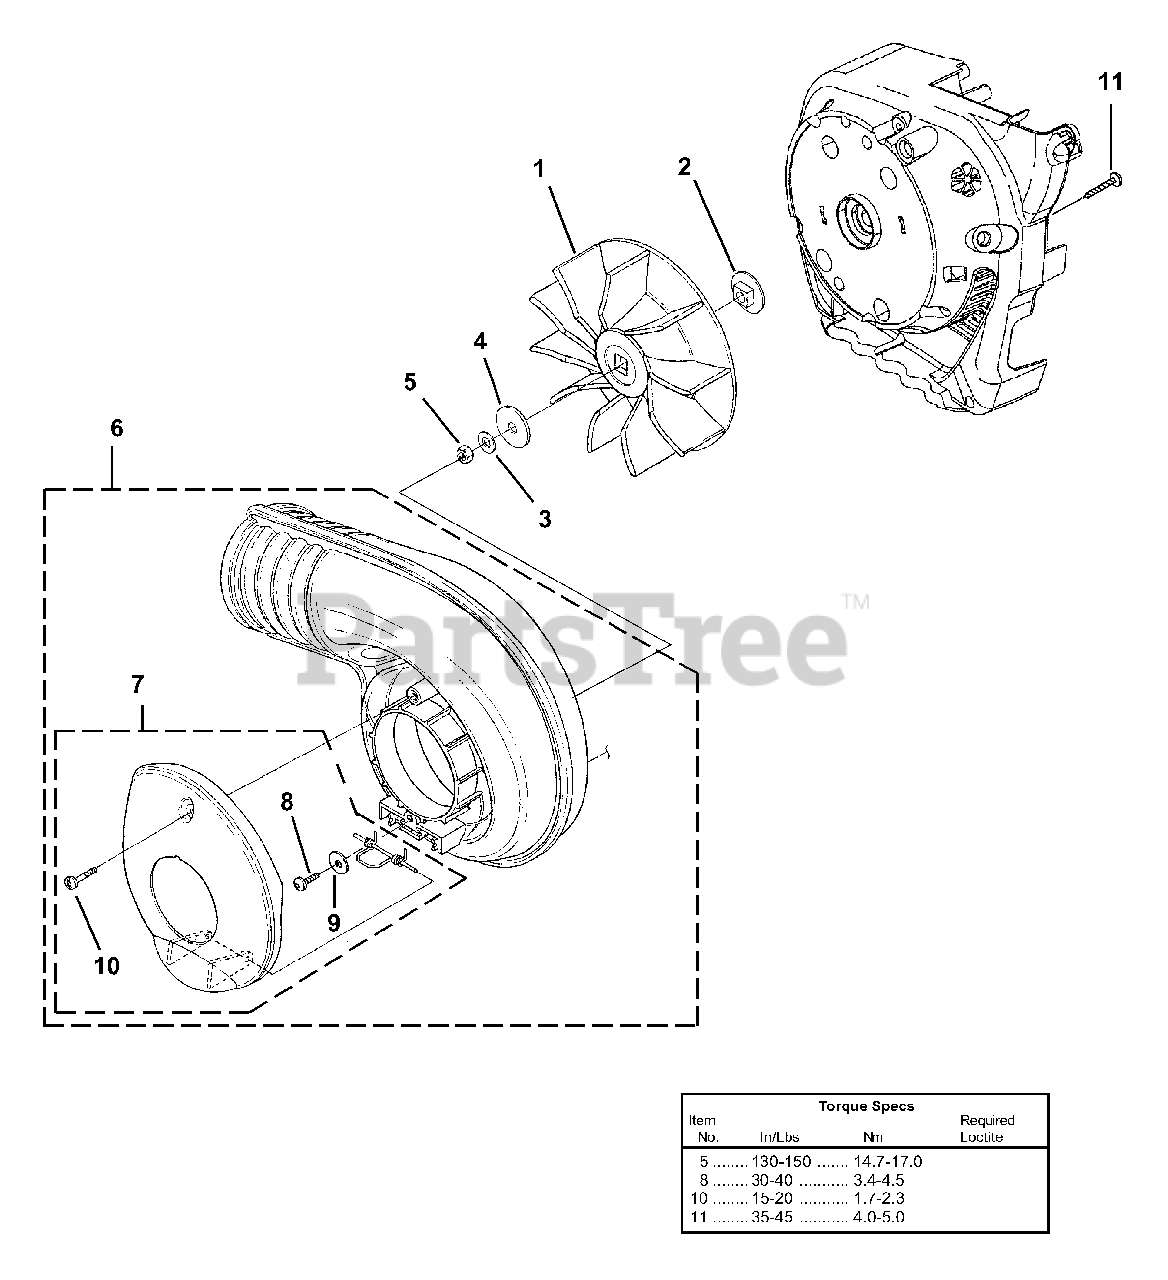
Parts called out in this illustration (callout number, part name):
2	Adapter, Fan
3	Washer, Belleville
4	Washer, Flat
5	Nut (3/8-24)
6	Volute W/Door Assembly
7	Access Door
8	Screw, Thread Forming (10-14 X 1/2)
10	Screw, Machine (10-24 X 3/4)
11	Screw, Plastite (10-14 X 7/8)
